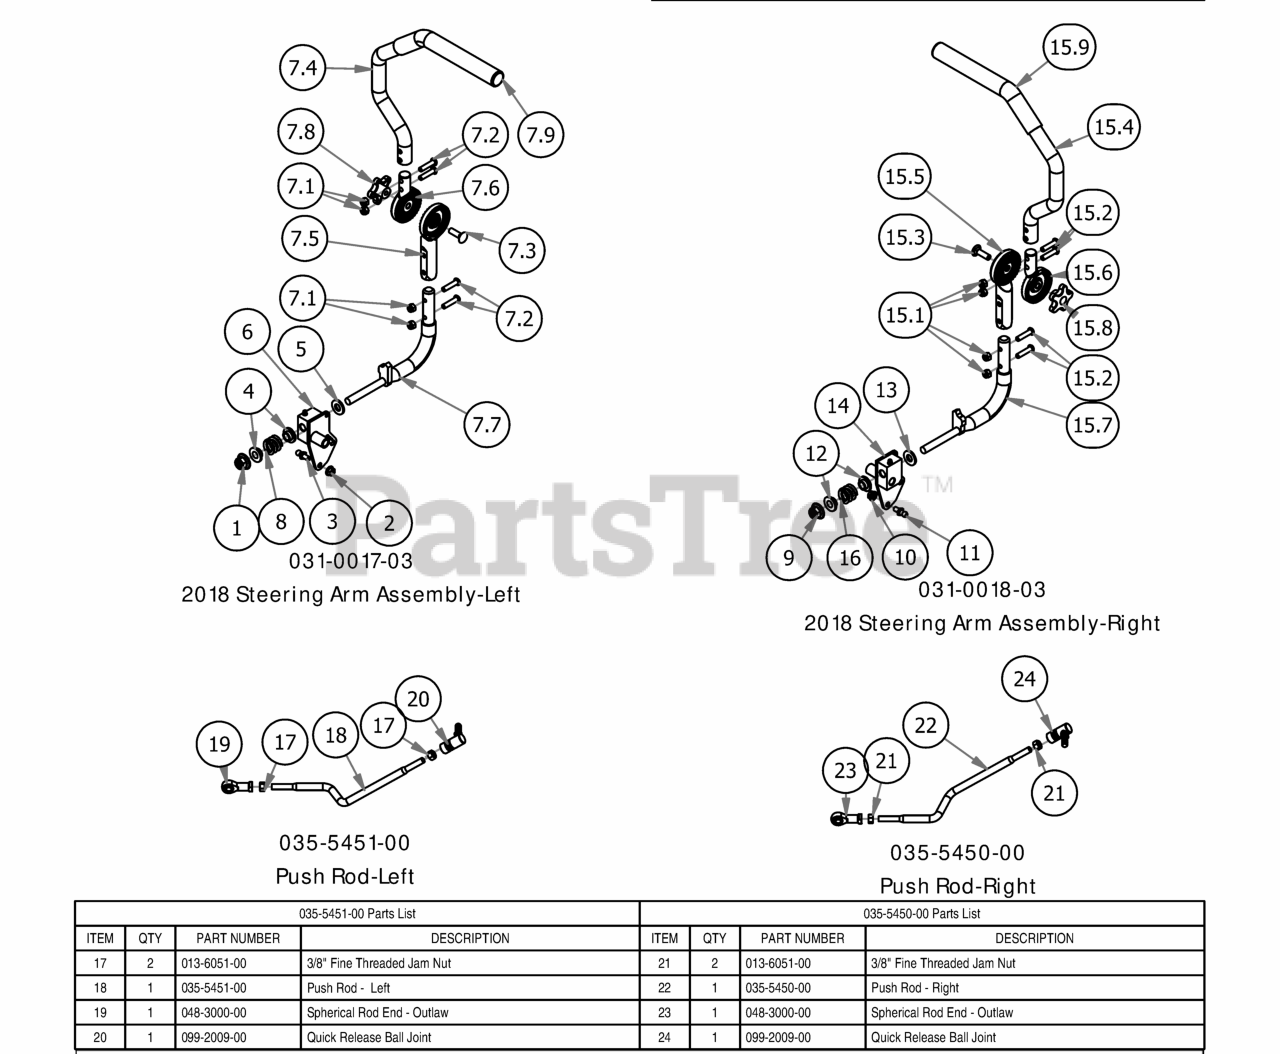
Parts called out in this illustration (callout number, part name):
1	1/2-13 Nylon Flange Nut
2	5/16" Flange Nut
3	10mm Damper Ball Stud-Steering
4	.515 ID Nylon Shoulder Washer
5	.505 Nylon Spacer
6	2017 Drive Lever Housing - Left
7	2018 Adjustable Steering Arm - Left
7.1	5/16-18 Nylock Insert Locknut
7.2	5/16-18 UNC X 1-3/8" BHCS, TORX DRIVE, GR 5
7.3	3/8" x 1 1/4" Carriage Bolt
7.4	Upper Tube-Adjustable Steering
7.5	2018 Lower Adjuster - Steering Arm- Left
7.6	2018 Upper Adjuster - Steering Arm- Left
7.7	Steering Arm Elbow (Left)
7.8	Black Knob for Adjustable Steering Arm
7.9	Rubber Grip
8	Drive Lever Spring
9	1/2-13 Nylon Flange Nut
10	5/16" Flange Nut
11	10mm Damper Ball Stud-Steering
12	.515 ID Nylon Shoulder Washer
13	.505 Nylon Spacer
14	2017 Drive Lever Housing - Right
15	2018 Adjustable Steering Arm - Right
15.1	5/16-18 Nylock Insert Locknut
15.2	5/16-18 UNC X 1-3/8" BHCS, TORX DRIVE, GR 5
15.3	3/8" x 1 1/4" Carriage Bolt
15.4	Upper Tube-Adjustable Steering
15.5	2018 Lower Adjuster - Steering Arm- Right
15.6	2018 Upper Adjuster - Steering Arm- Right
15.7	Steering Arm Elbow (Right)
15.8	Black Knob for Adjustable Steering Arm
15.9	Rubber Grip
16	Drive Lever Spring
17	3/8" Fine Threaded Jam Nut
18	Push Rod - Left
19	Spherical Rod End - Outlaw
20	Quick Release Ball Joint
21	3/8" Fine Threaded Jam Nut
22	Push Rod - Right
23	Spherical Rod End - Outlaw
24	Quick Release Ball Joint
